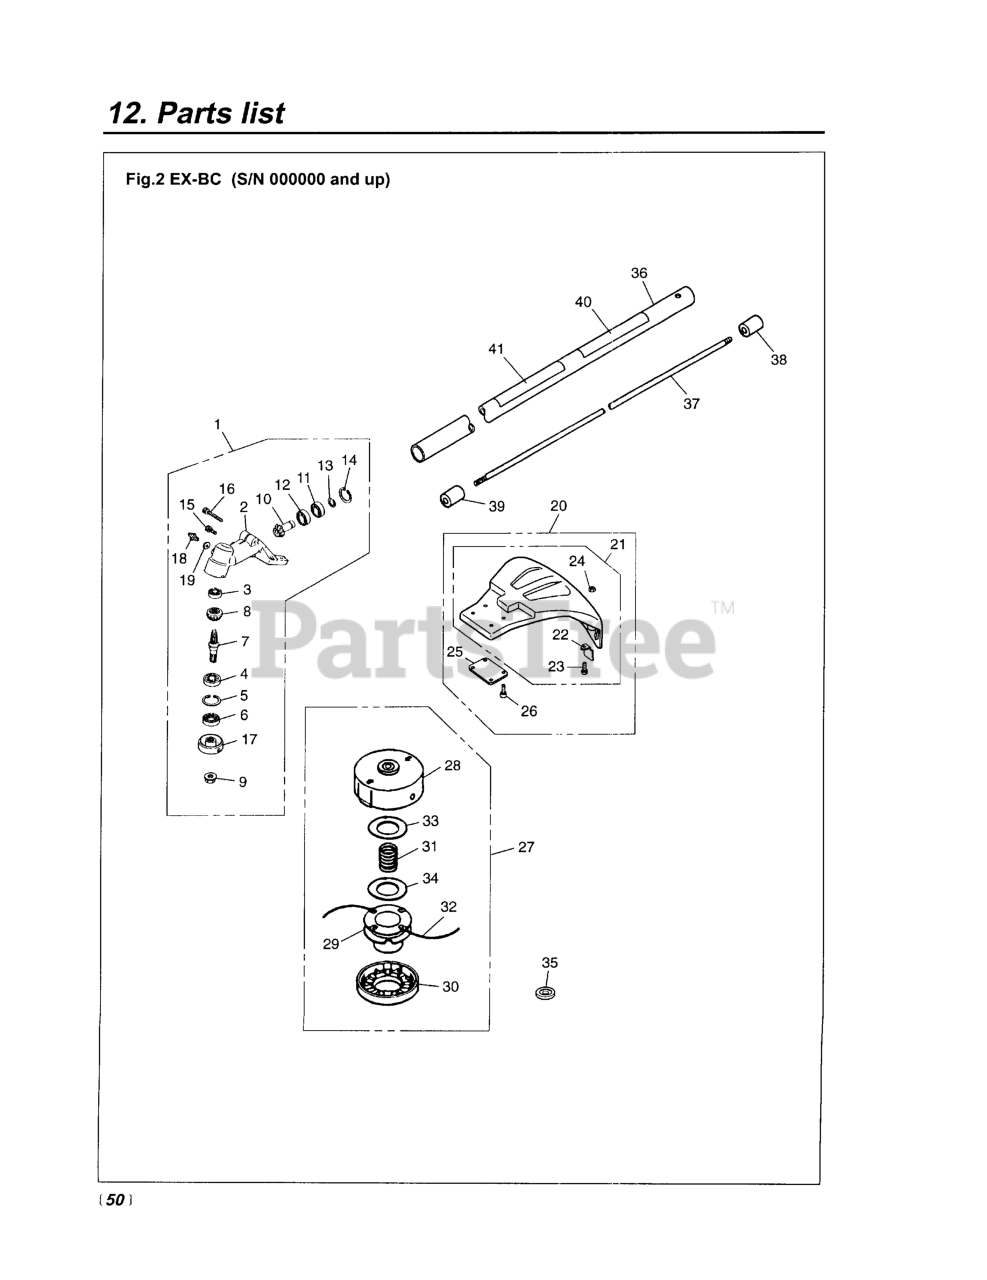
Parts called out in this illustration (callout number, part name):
1	GEARCASE ASSY (RPLS -13000)
2	GEARCASE
3	BEARING (RPLS T3300-13521)
4	BEARING (RPLS T3403-13510)
5	RING, SNAP, M26 X 1.2
6	SEAL, OIL
7	SHAFT
8	GEAR
9	NUT
10	PINION
11	BEARING (RPLS T3300-13531)
12	BEARING (RPLS T3403-13530)
13	RING, SNAP (RPLS T3300-13330)
14	RING, SNAP, M24 x 1.2
15	BOLT, M5 X 10
16	BOLT
17	HOLDER (A)
18	FITTING, GREASE
19	WASHER, M6 X .8
20	GUARD ASSY (RPLS -24000)
21	GUARD COMP (RPLS. -24100)
22	BLADE (RPLS T3002-24120)
23	SCREW
24	NUT
25	PLATE
26	BOLT (USE 3310-31720)
27	4
28	CASE (RPLS -15112)
29	HOLDER, CORD (RPLS -15141)
30	COVER (RPLS -15130)
31	SPRING (RPLS -99161)
32	CORD
33	PLATE, LARGE
34	PLATE, SMALL
35	HOLDER (B)
36	PIPE COMPLETE
37	SHAFT
38	JOINT, SHAFT (RPLS -12240)
39	SPACER
40	PLATE, NAME (BC-EX)
41	PLATE, CAUTION
